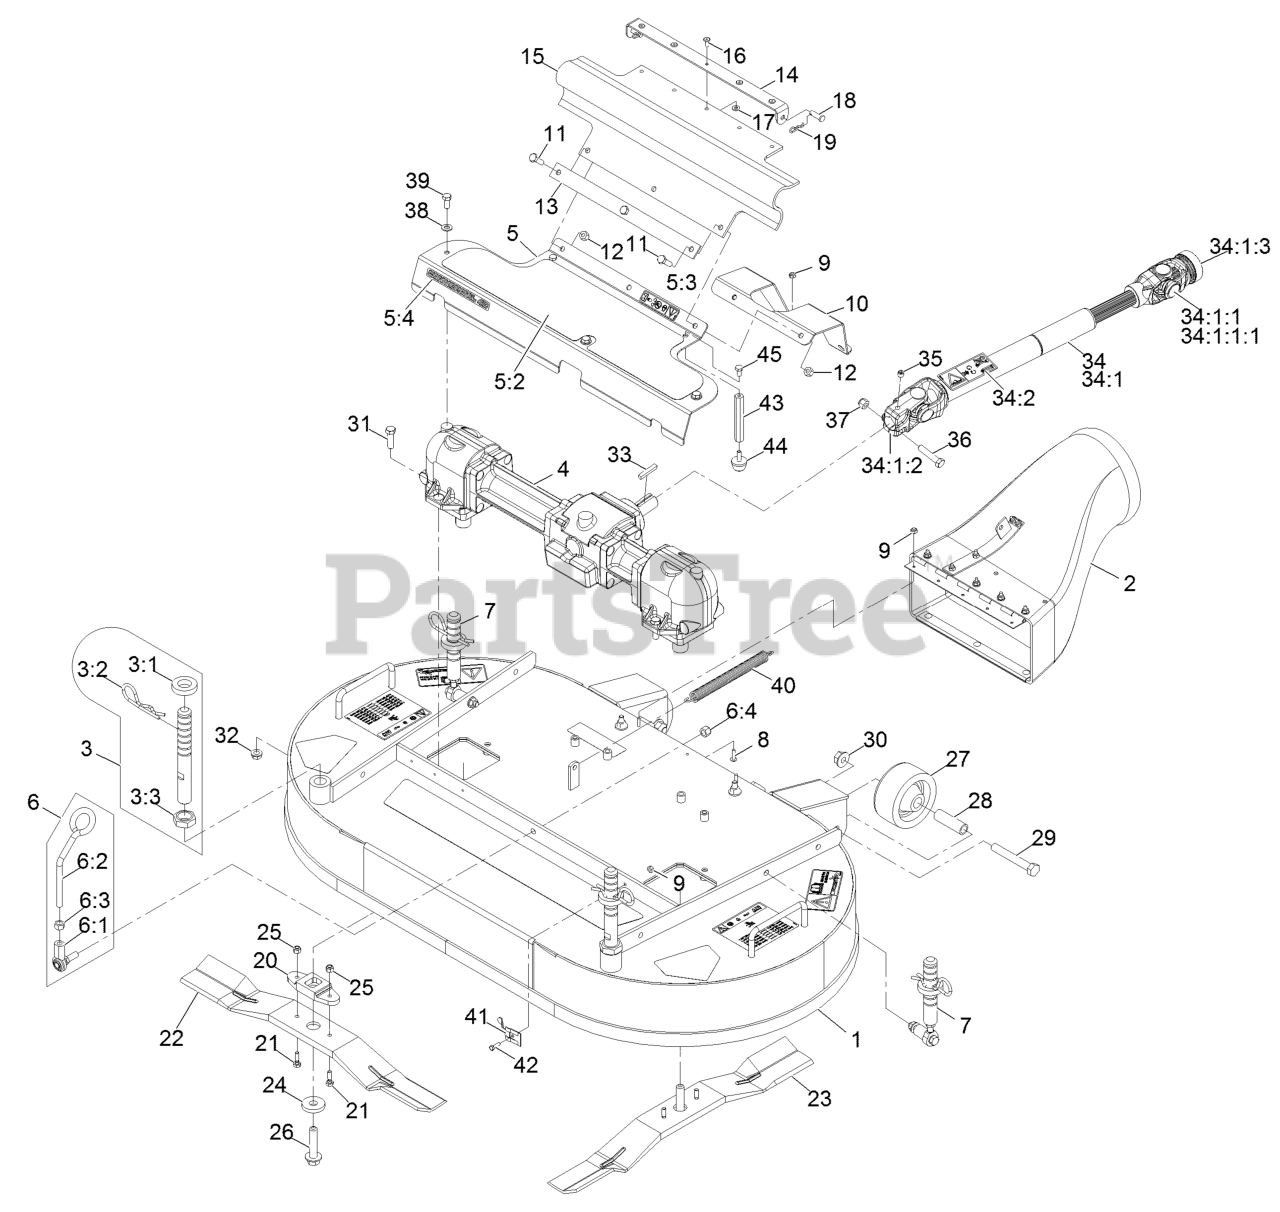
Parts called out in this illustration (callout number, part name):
1	DECK ASM
2	DISCHARGE TUBE ASM
3	FRONT DECK HEIGHT ADJUST
3:1	SPACER-DECK SUPPORT
3:2	PIN-CUT HEIGHT
3:3	NUT-JAM
4	GEARBOX ASM
5	ASM,GEARBOX COVER 42 W/DE
5:2	PAD-ANTI SKID
5:3	DECAL-DANGER
5:4	Decal-Commercial 42
6	DECK LATCH ASM
6:1	BALLJOINT-RH
6:2	LATCH-DECK
6:3	NUT-HEX
6:4	NUT-LOCK
7	REAR DECK HEIGHT ADJUST A
8	SCREW-HEAD, TRUSS
9	NUT-LOCK, NI
10	GUARD-DRIVE SHAFT
11	SCREW-HH
12	NUT-LOCK, NI
13	STRAP-DRIVE, LINE COVER
14	BRACKET-GUARD, PTO
15	GUARD-PTO
16	RIVET-BLIND
17	WASHER-FLAT
18	PIN-CLEVIS
19	PIN-COTTER
20	DRIVER-BLADE
21	BOLT-SHEAR
22	BLADE,22 INCH RH
23	BLADE,22 INCH LH
25	NUT-LOCK, NI
26	BOLT-BLADE
27	ROLLER-DECK
28	SPACER-ROLLER
29	SCREW-HH
30	NUT-HHF
31	SCREW-HH
32	NUT-HHF, WHIZ
33	KEY-SQUARE
34	DRIVE SHAFT ASM
34:1	Drive Shaft-Telescoping
34:1:1	U-JOINT KIT
34:1:1:1	FITTING-GREASE
34:1:2	YOKE-KEYED
34:1:3	YOKE-QUICK DISCONNECT
34:2	DECAL-DANGER, DRIVELINE
35	SCREW-SET, HSH
36	SCREW-HH
37	NUT-LOCK, NI
38	WASHER-PLAIN
39	SCREW-HH
40	SPRING-EXTENSION
41	CLIP-DECK, HOLD UP ROD
43	STAND-OFF
45	SCREW-HH
